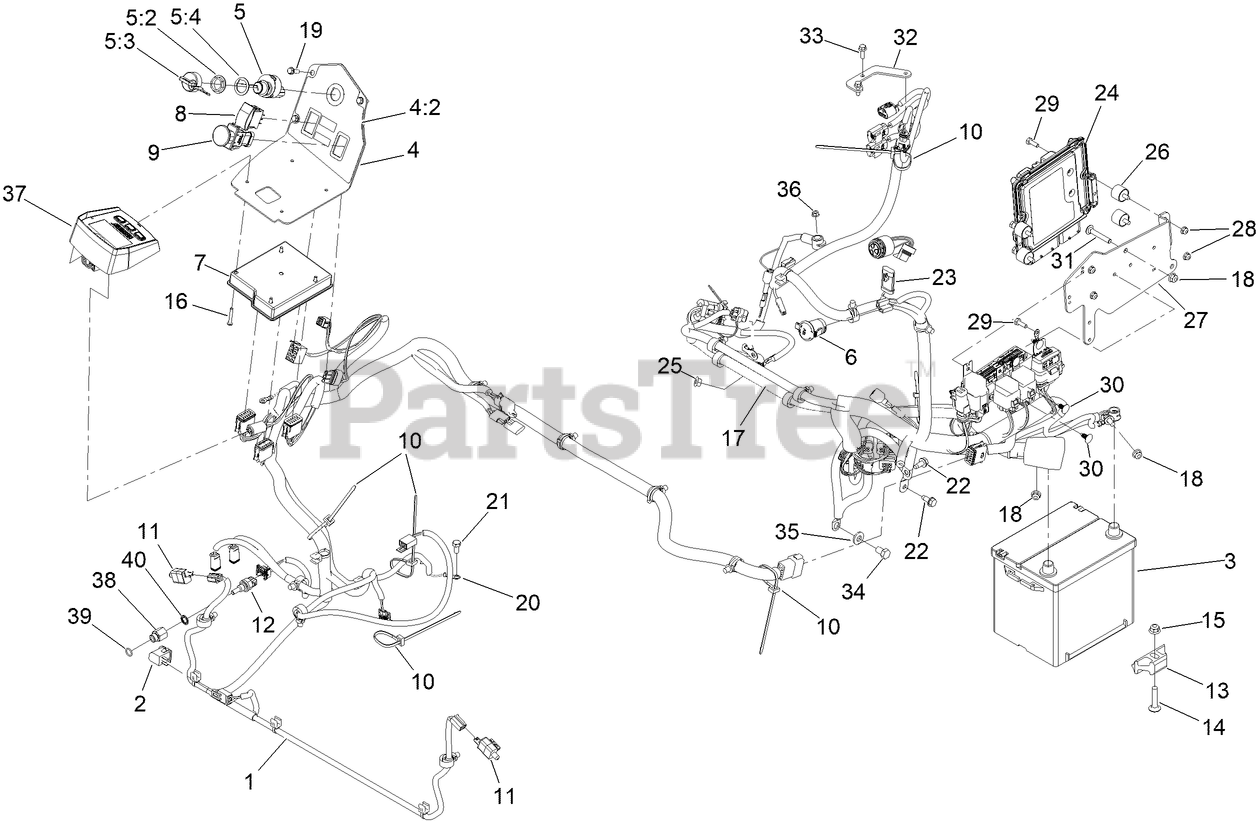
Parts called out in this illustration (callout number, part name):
1	HARNESS-WIRE
2	SWITCH-BAIL
3	BATTERY-DRY
4	CONSOLE ASM
4:2	DECAL-CONTROL PANEL
5	IGNITION SWITCH ASM
5:2	NUT-MOUNTING
5:3	IGNITION KEY SET
5:4	WASHER-BACKUP
6	PORT-POWER, 12V
7	MODULE-MCU
8	SWITCH
9	SWITCH-PTO, SEALED
10	TIE-CABLE
11	SWITCH
12	SENSOR-TEMPERATURE
13	RETAINER-BATTERY
14	SCREW-CARR
15	NUT-HF, NI
16	SCREW-PPH
17	CABLE-BATTERY
18	NUT-HF, NI
19	SCREW-HWH
20	HARNESS-WIRE, JUMPER
21	BOLT
22	SCREW-HWHTF
23	HARNESS-WIRE, YANMAR
24	CONTROLLER-ENGINE
25	NUT-HF
26	MOUNT-CYLINDRICAL
27	MOUNT-CONTROL UNIT, ENGINE
28	NUT-HF
29	SCREW-HH
30	PLUG-PLASTIC
31	BOLT-CARR
32	BRACKET-WIRING, ENGINE
33	SCREW-HHF
34	SCREW-HH
35	WASHER-BELLEVILLE
36	NUT-HF
37	MODULE-HORIZON
38	FITTING-STR, 6MORB-M12, STL, CZ
39	O-RING
40	WASHER-SEAL, M12
